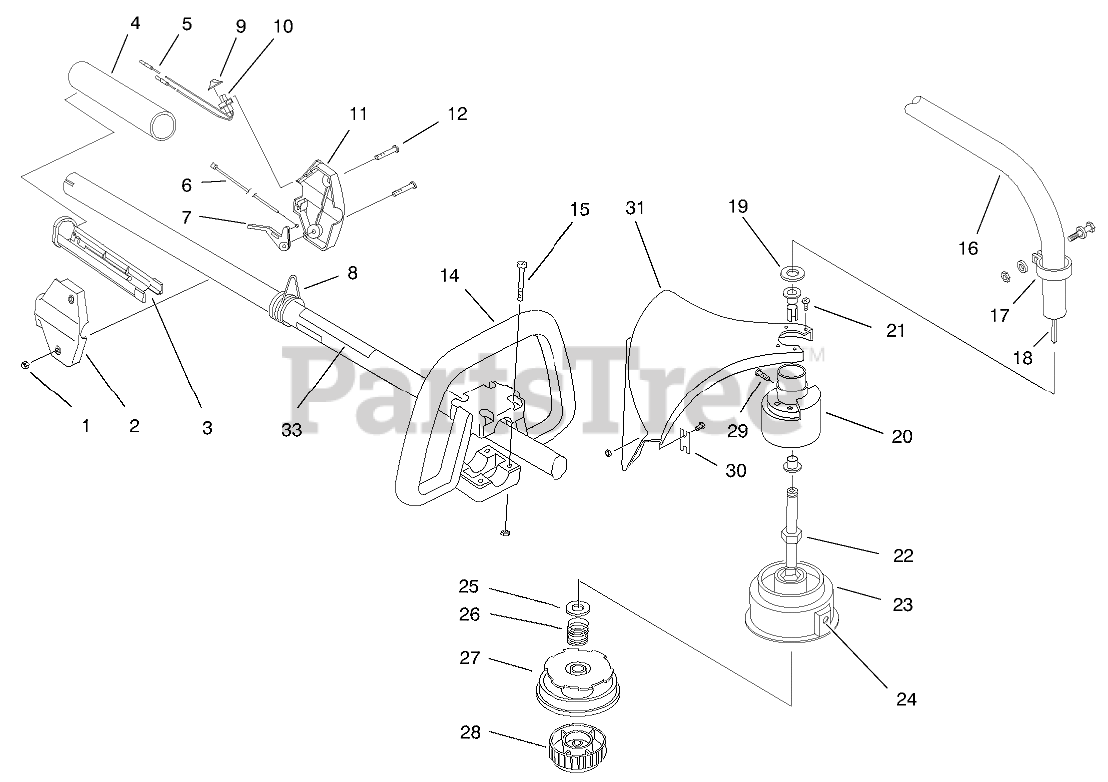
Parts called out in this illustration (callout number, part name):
1	NUT-LOCK, NI
2	RH HOUSING
3	TROUGH 1"
4	GRIP - RUBBER
5	LEAD WIRE ASM
6	THROTTLE CABLE
7	THROTTLE LEVER
8	Clip-Shoulder Strap
9	SWITCH COVER
10	SWITCH
11	LH HOUSING
14	HANDLE W/HARDWARE
15	HARDWARE - HANDLE
16	ASM - DRIVE SHAFT HSG
17	CLAMP ASM - UPPER
18	Drive Shaft
20	BUSHING HSG ASM
21	GUARD MTG SCREW ASM
22	Shaft-Spool
23	OUTER SPOOL EYELET ASM
24	EYELET
25	RETAINER WASHER(SET OF 10)
26	SPRING
27	REEL - INNER
28	Assy.-Bump Head
29	ANTI-ROTATION SCREW
30	BLADE ASM
31	Guard and Blade Asm. (Incl. Ref. # 30)
33	Decal-Safety Symbol
